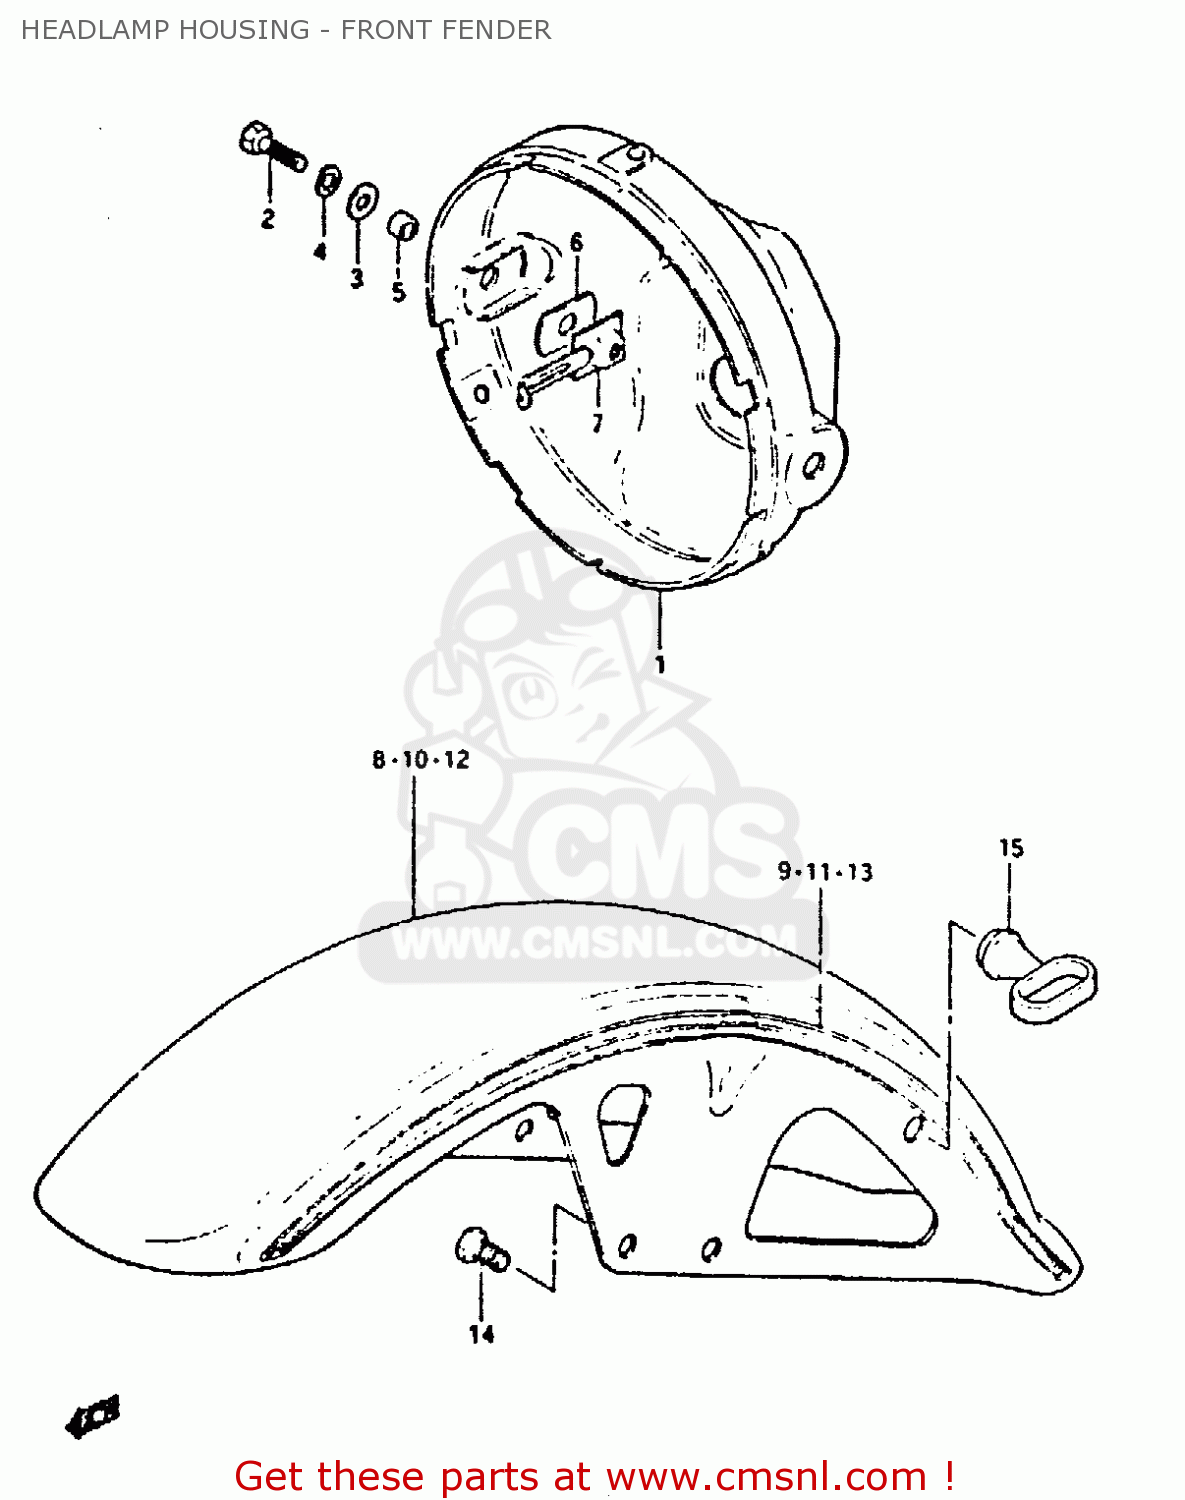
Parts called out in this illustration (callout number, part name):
1	HOUSING,HEADLAMP
2	BOLT
3	WASHER
4	LOCK WASHER
5	SPACER (8.8X12X7)
6	CUSHION
7	PLATE,HEADLAMP HOUSING
8	FENDER,FRONT
9	TAPE,FRONT FENDER
10	FENDER,FRONT
11	TAPE,FRONT FENDER
14	BOLT 8X16
15	GUIDE,CABLE
